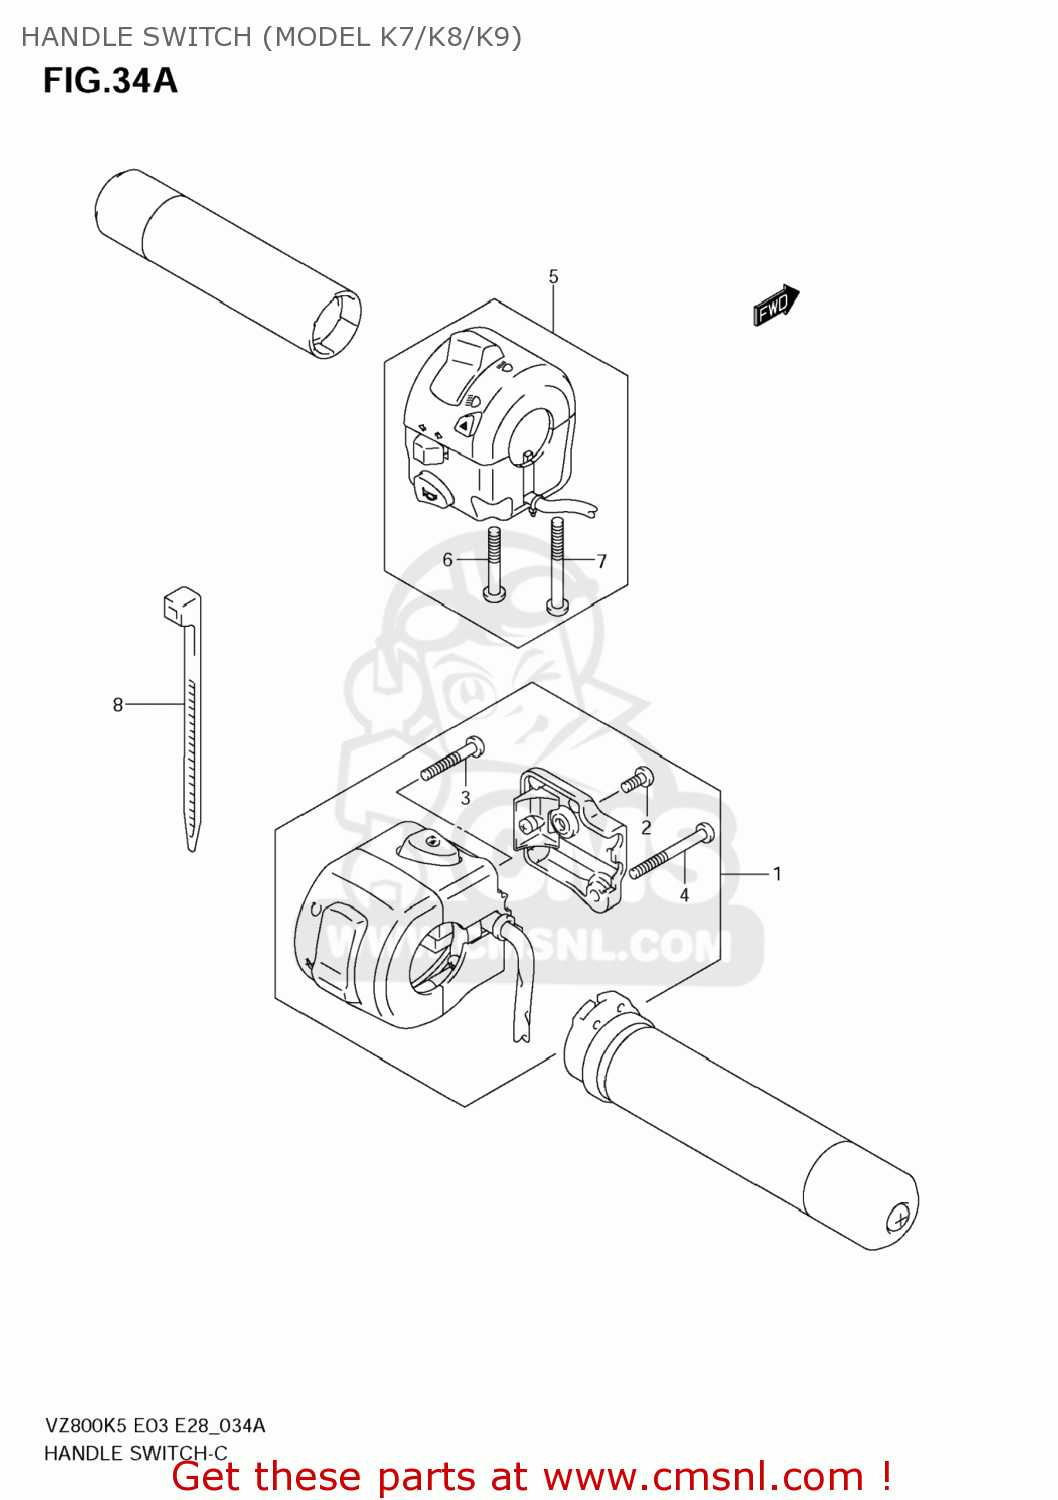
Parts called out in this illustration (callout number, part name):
1	SWITCH ASSY,HA
2	SCREW
3	SCREW
4	SCREW
5	SWITCH ASSY,HANDLE,L
6	SCREW
7	SCREW
8	CLAMP(L:145)
